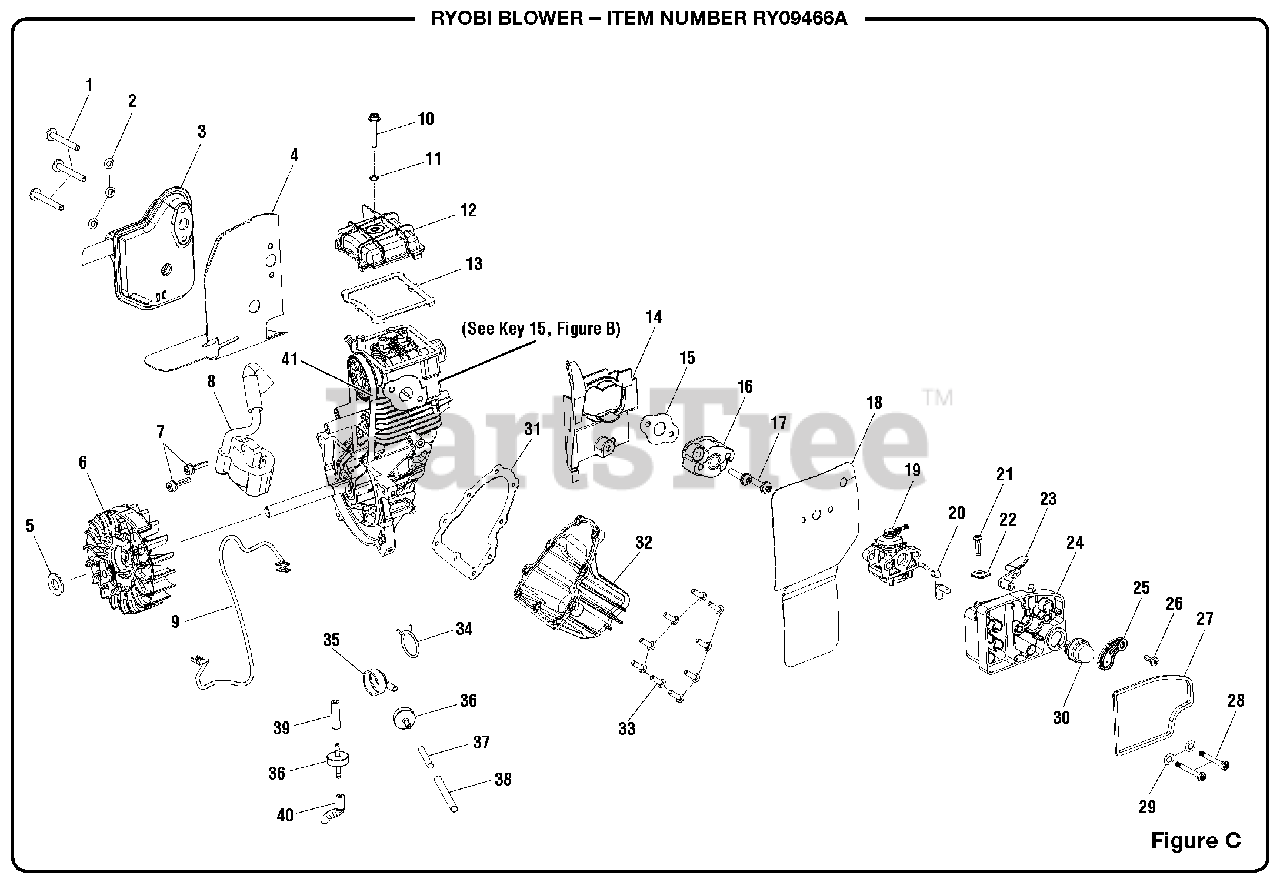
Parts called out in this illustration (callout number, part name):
1	Screw (M5 x 42 mm, T25 Truss Hd.)
2	Lock Washer (M5)
4	Muffler Gasket
5	Washer (ID9.70 x OD20 x 1.59t)
6	Flywheel Assembly
7	Screw (M4 x 19 mm, T20 Torx Pan Hd.)
8	Ignition Module
9	Lead Assembly
10	Screw (M4 x 27 mm, T20 Torx Truss Hd.)
12	Cam Cover
14	Air Baffle
15	Heat Dam Gasket
17	Screw (M5 x 23 mm, T25 Torx pan Hd.)
19	Carburetor
20	Fuel Hose (90 mm)
21	Screw (M4 x 16 mm, T20 Pan Hd.)
23	Choke Lever
24	Air Box Base
25	Choke Plate
26	Screw (M4 x 12 mm, T20 Torx Pan Hd.)
27	Air Box Seal
28	Bolt (M5 x 48 mm, T20 Torx hd.)
29	Washer (ID5 x OD9.90 x 1t)
30	Primer
33	Screw (M4 x 12 mm, T20 Torx Hd.)
35	Breather Fitting
36	Check Valve
37	Fuel Hose (53 mm)
38	Shield Sleeve (50 mm)
39	Breather Hose (34 mm)
40	Breather Hose (25 mm)
41	Timing Belt
